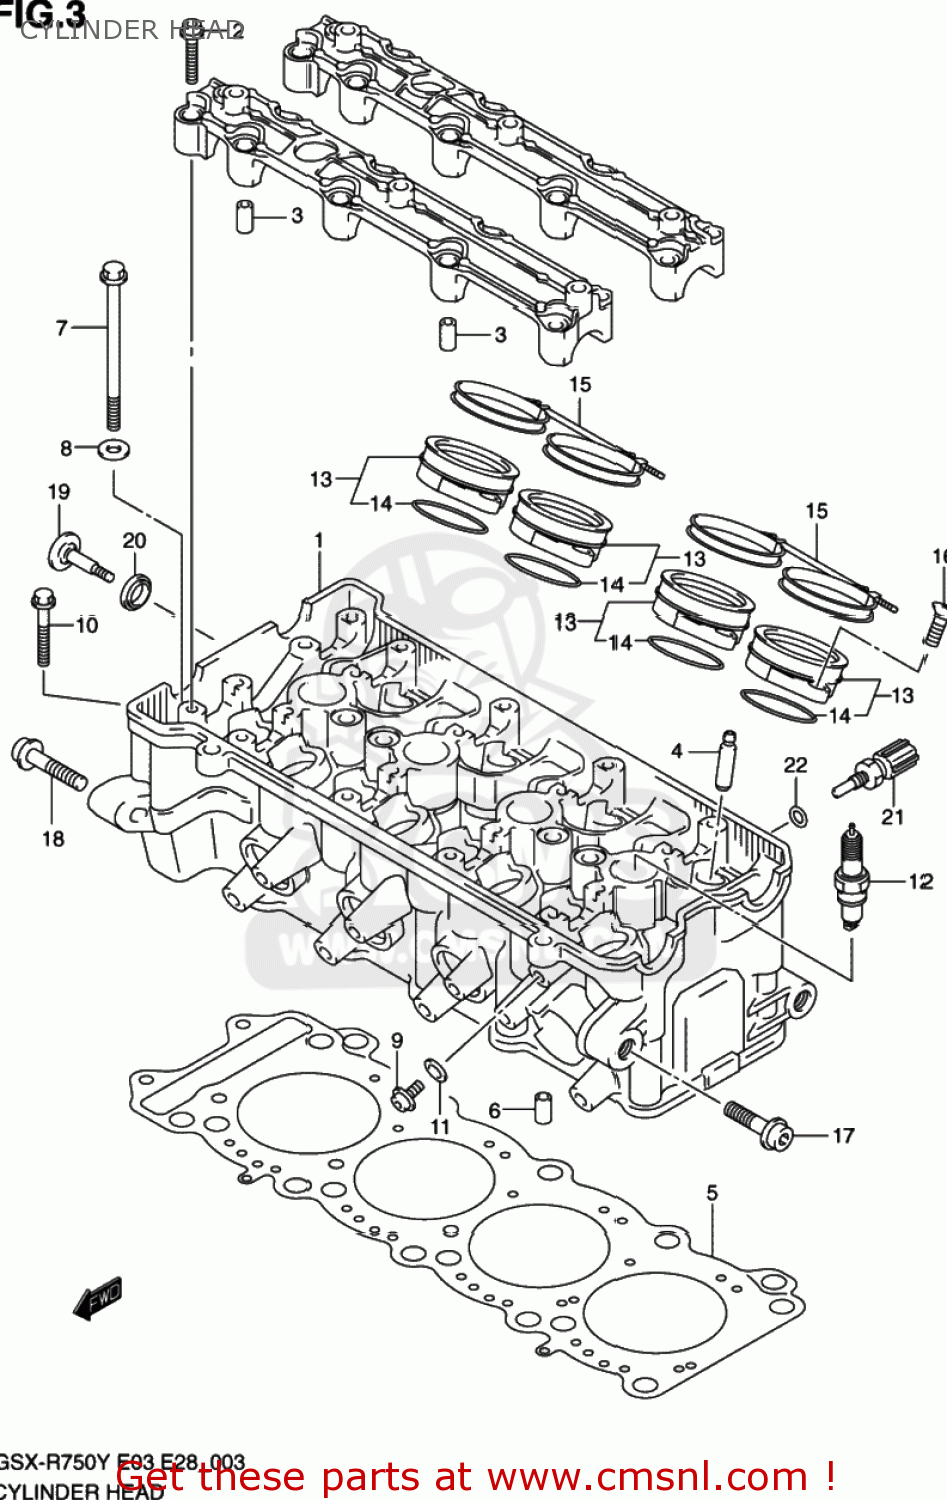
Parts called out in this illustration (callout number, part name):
1	HEAD ASSY,CYLINDER
2	BOLT
3	PIN(6.2X8X16)
4	GUIDE,VALVE
5	GASKET,CYLINDER HEAD (NAS)
6	PIN
7	BOLT 10X105
8	WASHER(10.5X19X2)
9	BOLT(6X12)
10	BOLT,CYL.OIL P
11	GASKET(5.8X13X1.2) (NAS)
12	PLUG,SPARK(CR8E)
13	PIPE ASSY,INTAKE
14	O RING(D:2.4,ID:47X42)
15	CLAMP,INTAKE PIPE
16	SCREW ,6X16
17	BOLT(10X45)
18	BOLT(10X55)
19	BOLT,CYL HEAD SIDE FACE
20	WASHER,HEAD COVER
21	SENSOR,WATER TEMP
22	GASKET(12X17X1) (NAS)
